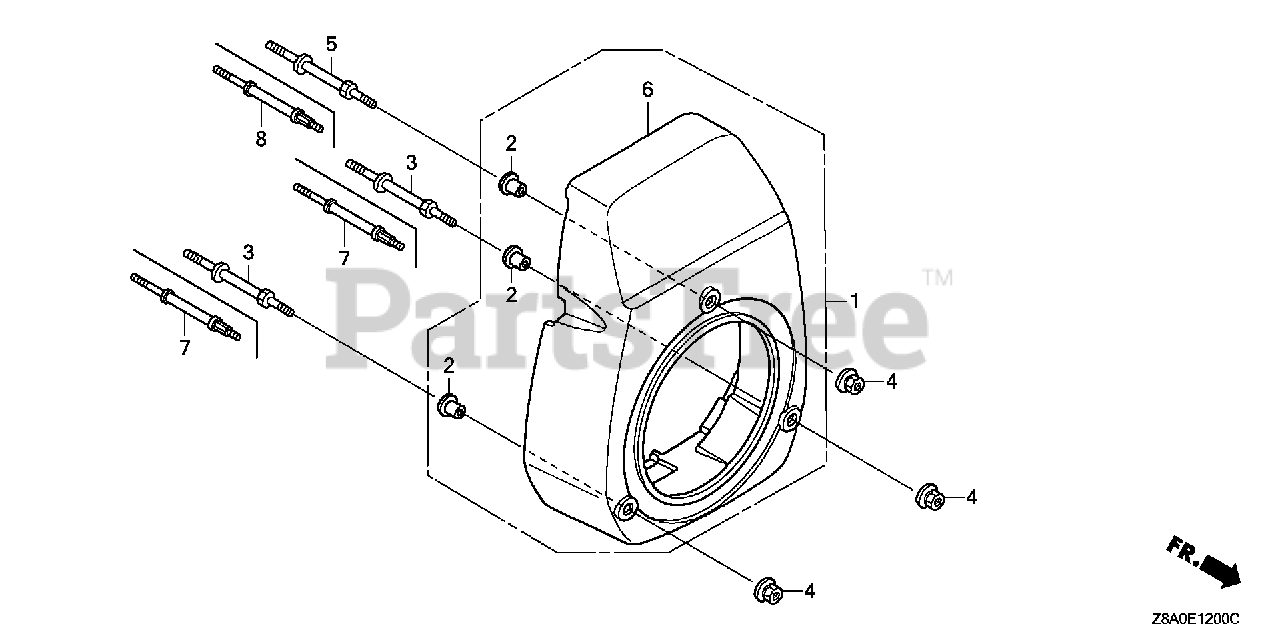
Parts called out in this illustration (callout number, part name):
4	NUT, FLANGE (6MM)
6	COVER, FAN *NH1* (BLACK)
6	COVER, FAN *R280* (POWER RED)
7	BOLT, STUD (FAN COVER)
8	BOLT, STUD (FAN COVER)
